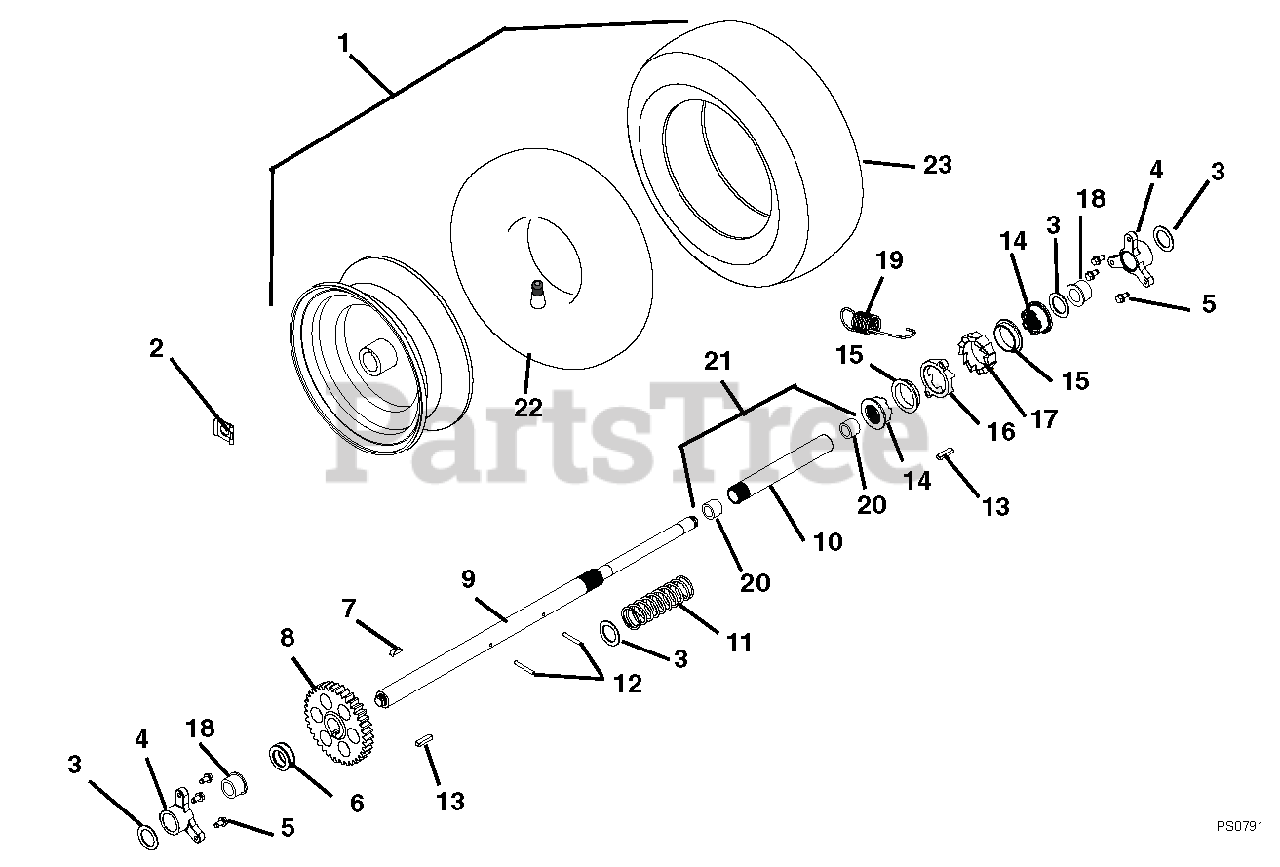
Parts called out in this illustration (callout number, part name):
1	TIRE/WHEEL, RH 16X6.50-8 DIFF
2	CLIP, SNAP .625 DIA
3	WSHR-FL-STL 1.010X1.505X.062YZ
4	BUSHING, RAKE SHAFT 1"
5	SCR-TAP .25-20X.50 HWH TR YWZ
6	SPACER 1.008X1.503X.605
7	KEY-WDRF .25X.750X.313 SAE91
8	GEAR, SPUR
9	AXLE, DIFFERENTIAL-LONG
10	AXLE, DIFFERENTIAL-SHORT
11	SPRING, COMPRESSION
12	PIN-ROLL .188X1.50
13	KEY-RECT .25X.188X1.00
14	CLUTCH, DOG - SLIDING
15	BUSHING, FLANGE
16	GEAR, CLUTCH
17	GEAR, RATCHET
18	BSHG-FLG SPLIT NYLINER 1.0" HP
19	SG-TENS .06X.62X2.94
20	BSHG-SLV .706X.764X.75 BRZ
21	DECAL,FOOT
23	TIRE, 16X6.50-8 K478
